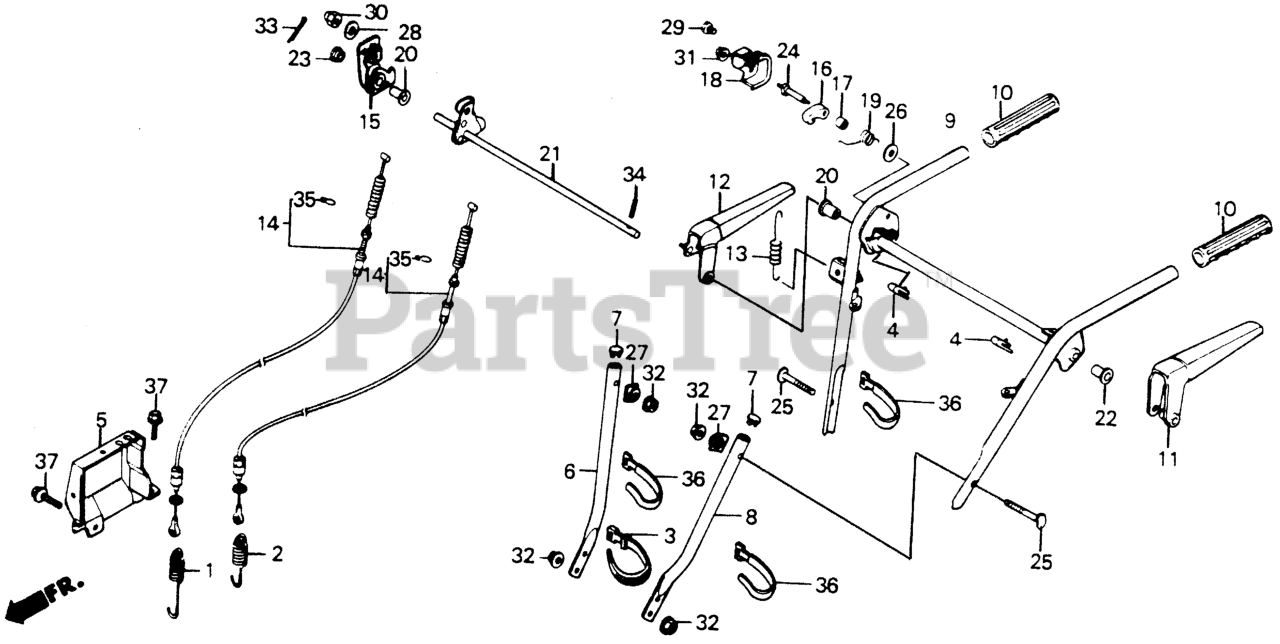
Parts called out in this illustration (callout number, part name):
1	SPRING, TENSIONER ROLLER
2	SPRING, TENSIONER ROLLER (AUGER)
3	BAND B1, CABLE Use up to Frame SN 1001879.
4	RUBBER, STOPPER
5	HOLDER, WIRE
6	HANDLE, R. (LOWER)
7	CAP, HANDLE (LOWER)
8	HANDLE, L. (LOWER)
9	PIPE, HANDLE (UPPER)
10	GRIP, HANDLE
11	LEVER, CLUTCH
12	LEVER, AUGER CLUTCH
13	SPRING, CLUTCH LEVER
14	CABLE, CLUTCH (NOT AVAILABLE)
15	BOSS, CAM LOCK
16	RATCHET, LEVER
17	COLLAR, RATCHET
18	COVER, RATCHET
19	SPRING, RATCHET
20	BUSH (13X22.5) (GRAY)
21	SHAFT, CLUTCH LEVER
22	BUSH (14MM)
24	BOLT, PIVOT (6MM)
25	BOLT, HANDLE HOLDER (8X41)
26	WASHER (10MM)
26	WASHER, THRUST (10MM)
27	WASHER, FRAME JOINT
28	WASHER (6MM)
29	BOLT, FLANGE (6X10)
30	NUT, CAP (6MM)
31	NUT, FLANGE (6MM)
32	NUT, FLANGE (8MM)
33	PIN, COTTER (3.0X18)
34	PIN, SPRING (4X16)
35	CLIP, TUBE (C9)
36	BAND B2, CABLE HARNESS
37	BOLT, FLANGE (6X16) Use from Engine SN 2056820.
